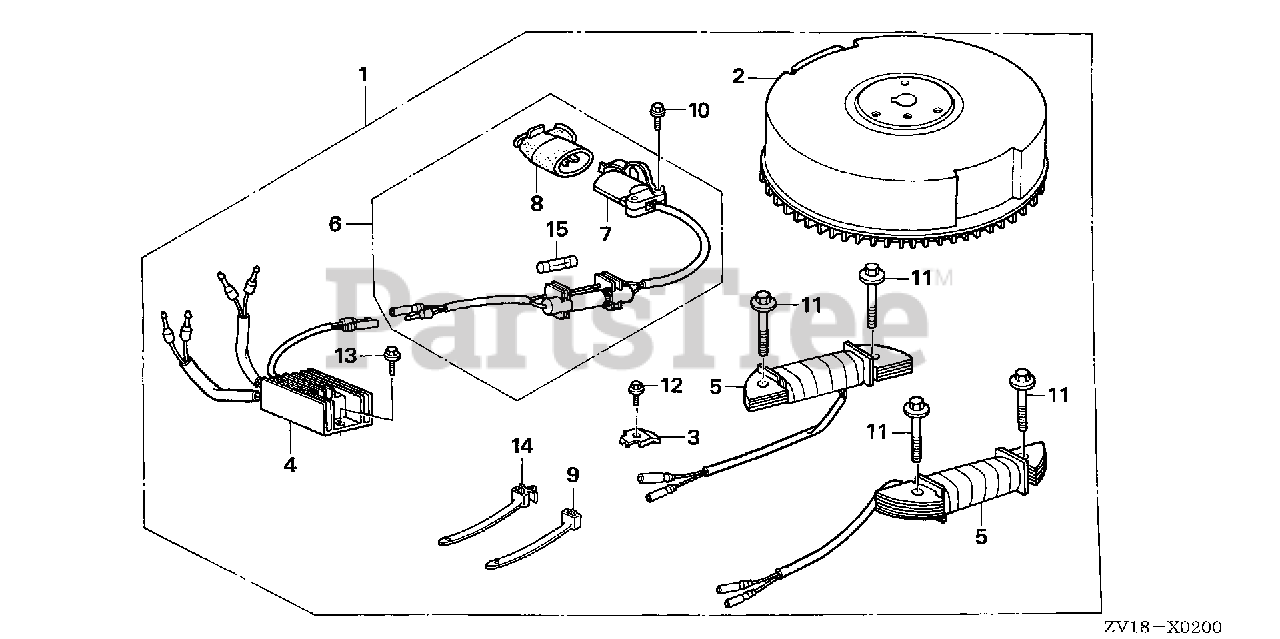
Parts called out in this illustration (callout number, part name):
1	RECEPTACLE KIT, CHARGE *TBLACK* (BLACK)
2	FLYWHEEL *TBLACK* (CHARGE) (BLACK)
3	CLAMP, WIRE
4	RECTIFIER ASSY., REGULATOR
5	COIL ASSY., CHARGE (12V-1.5A)
6	RECEPTACLE ASSY., CHARGE Use from Engine SN 1308875.
7	RECEPTACLE
8	PLUG, RECEPTACLE
9	TIE, CABLE (NATURAL 2.4X92) Use up to Frame SN 1300359.
10	BOLT, FLANGE (5X22)
11	BOLT, FLANGE (6X28) (CT200)
12	BOLT, FLANGE (5X10)
13	BOLT, FLANGE (6X16)
14	BAND, CABLE
15	FUSE A (5A)
